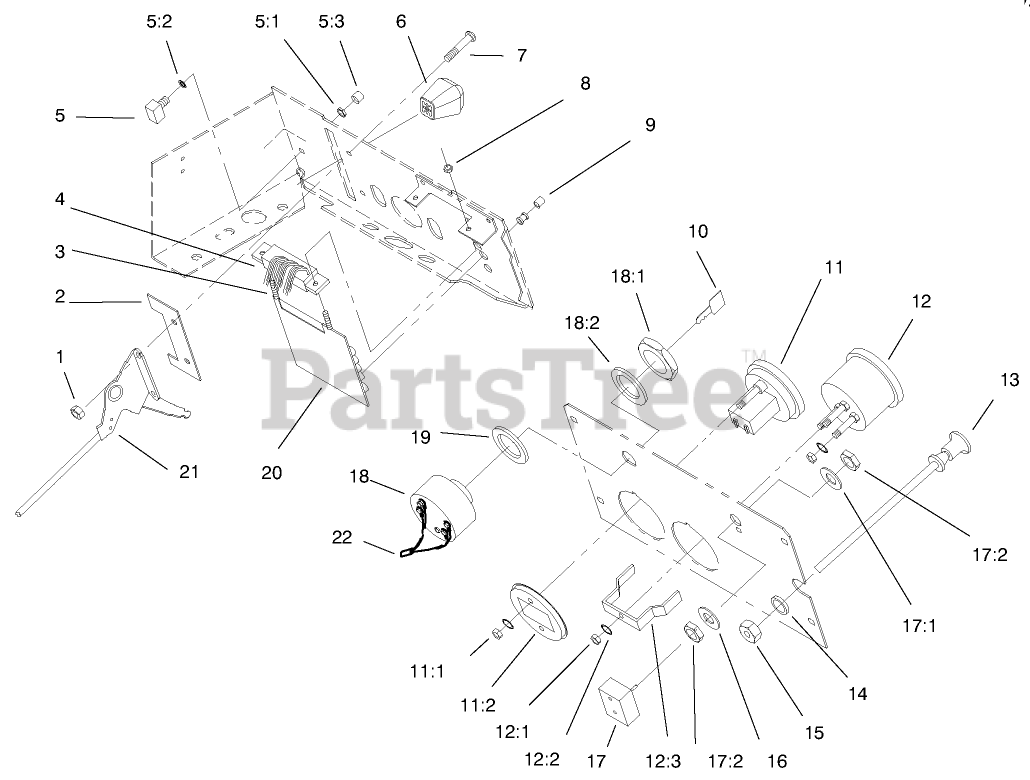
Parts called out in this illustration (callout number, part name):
3	Screw
4	P.C. BOARD HARNESS
5	SWITCH-PUSH BUTTON
5:1	NUT F/W 116796
7	SCREW-PPH
8	NUT-HEX, NYL INS
9	ASSY LENS & BUSHING
10	KEY-IGNITION
11:1	NUT-HEX, KEPS
11:2	Retainer
12	VOLTMETER
12:1	NUT-HEX
12:3	CLAMP-MOUNTING
13	CONTROL-CHOKE
14	WASHER-FLAT
15	NUT-HEX PALNUT
16	WASHER
17	SWITCH-LIGHTS
17:1	TAB-WASHER
17:2	*DISC**
18:2	WASHER-LOCK
19	WASHER
21	CONTROL-THROTTLE
